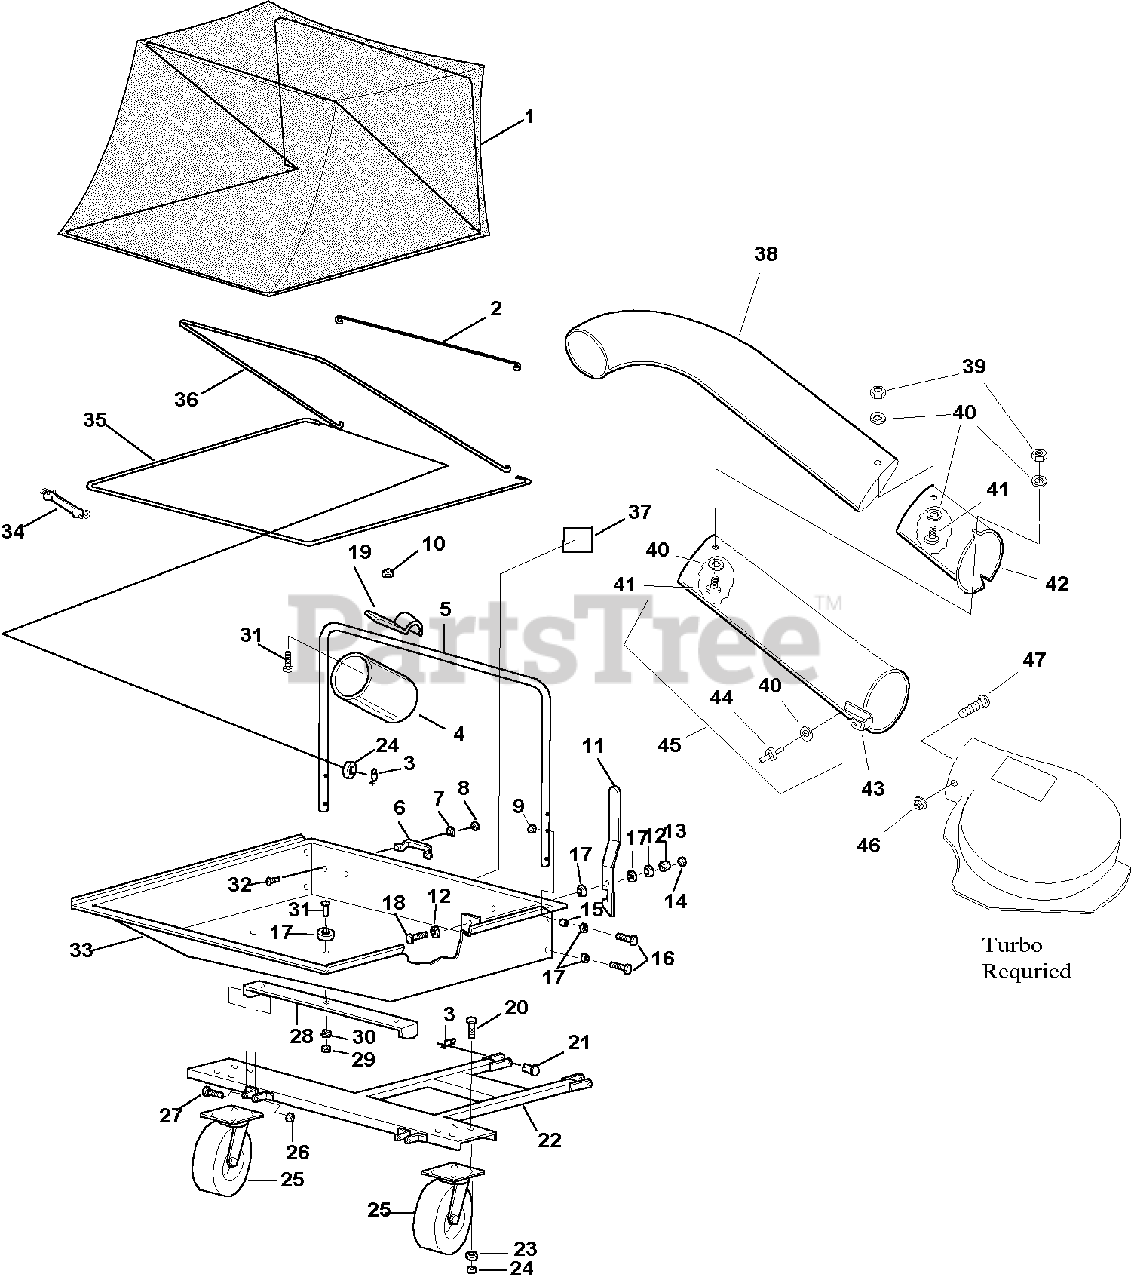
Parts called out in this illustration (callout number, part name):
1	COVER, Jrco, Cart
3	SAFETY, Pin
5	TUBE, Support
6	HANDLE, Lift
7	LOCKWASHER, Spring, 1/4-20
8	NUT, Hex, 1/4-20
9	NUT, Hex Centerlock, 5/16-18
10	NUT, Hex Nylock, 1/4-20
11	HANDLE, Latch
12	WASHER, Compression
13	NUT,Hex, 5/16-18
14	NUT, Hex Jam, 5/16-18
16	CAPSCREW, Hex Head, 5/16-18 X 1-1/2
17	WASHER, 5/16
18	CAPSCREW, Hex Head, 5/16-18 X 1-1/4
19	SLEEVE, Clamp
20	CAPSCREW, Hex Head 3/8-16 X 1
21	PIN, Round, Head, Drilled, 1/2 X 1-1/2
22	FRAME, Jrco, Cart
23	WASHER, 3/8
24	NUT, Hex Centerlock, 3/8-16
25	WHEEL Assembly, Swivel
26	NUT, Hex Centerlock, 1/2-13
27	CAPSCREW, Hex Head, 1/2-13 X 1-1/4
28	BRACKET, "U"
29	NUT, Hex, 5/16-18
30	LOCKWASHER, Spring, 5/16
31	SCREW, Truss Head Slotted, 5/16-18 X 3/4
32	CAPSCREW, Hex Head, 1/4-20 X 1/2
33	BOX, Jrco 44"
34	STRAP, Rubber
36	ROD, Support
37	DECAL, Maximum Capacity
38	ELBOW, Upper
39	NUT, Hex, Washer Assembly , #10-32
41	SCREW, Truss Head, #10-32 x 1/2
42	TUBE, Middle
43	CLIP, Spring
45	TUBE & SPRING ASSEMBLY, (Incl. Ref. Nos. 40, 43 & 44)
46	NUT, Hex, Flange Lock, 1/4-20
47	CARRIAGE BOLT, 1/4-20 x 5/8
